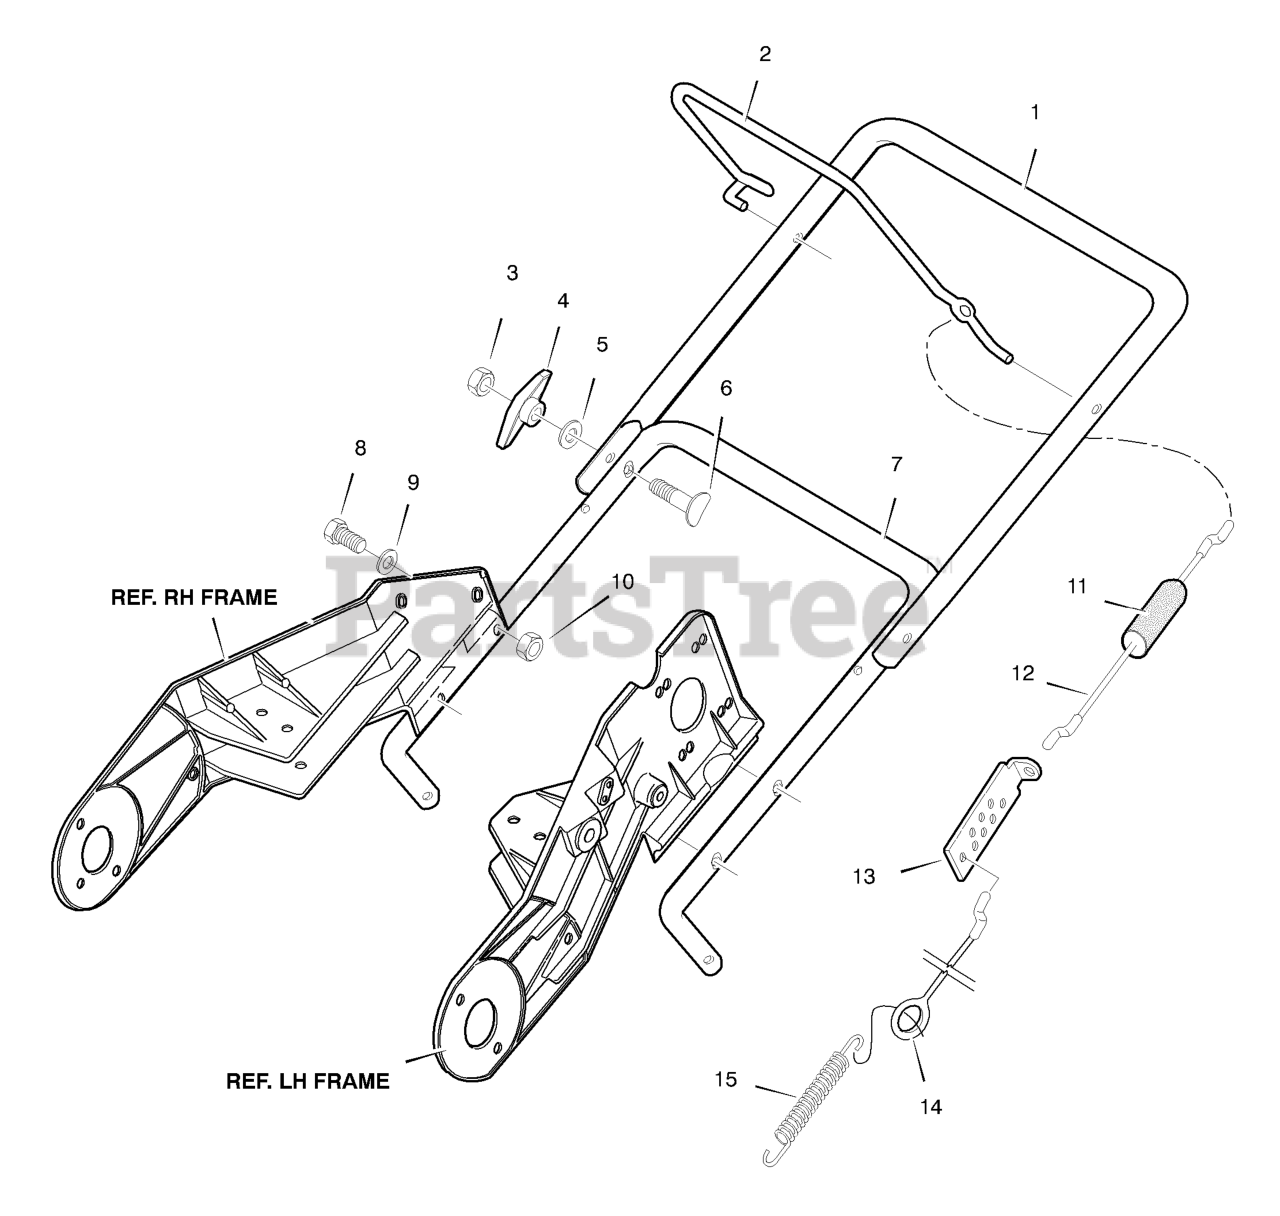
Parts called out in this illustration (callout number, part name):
1	HANDLE, UPPER
2	BAIL, CONTROL
3	NUT, 5/16-18 REGHEX
4	T-KNOB, PLASTIC
5	WASHER, FORM
6	BOLT, 5/16-18 x 2.00
7	HANDLE, LOWER
8	SCREW, 1/4-20 x 1.25
9	WASHER, FLAT
10	NUT, 1/4-20 HEXCTRNL
11	BOOT, CLUTCH SPRING
12	CABLE, UPPER CONTROL
13	BRACKET, CABLE ADJUST
14	CABLE, LOWER CONTROL
15	SPRING, EXTENSION
